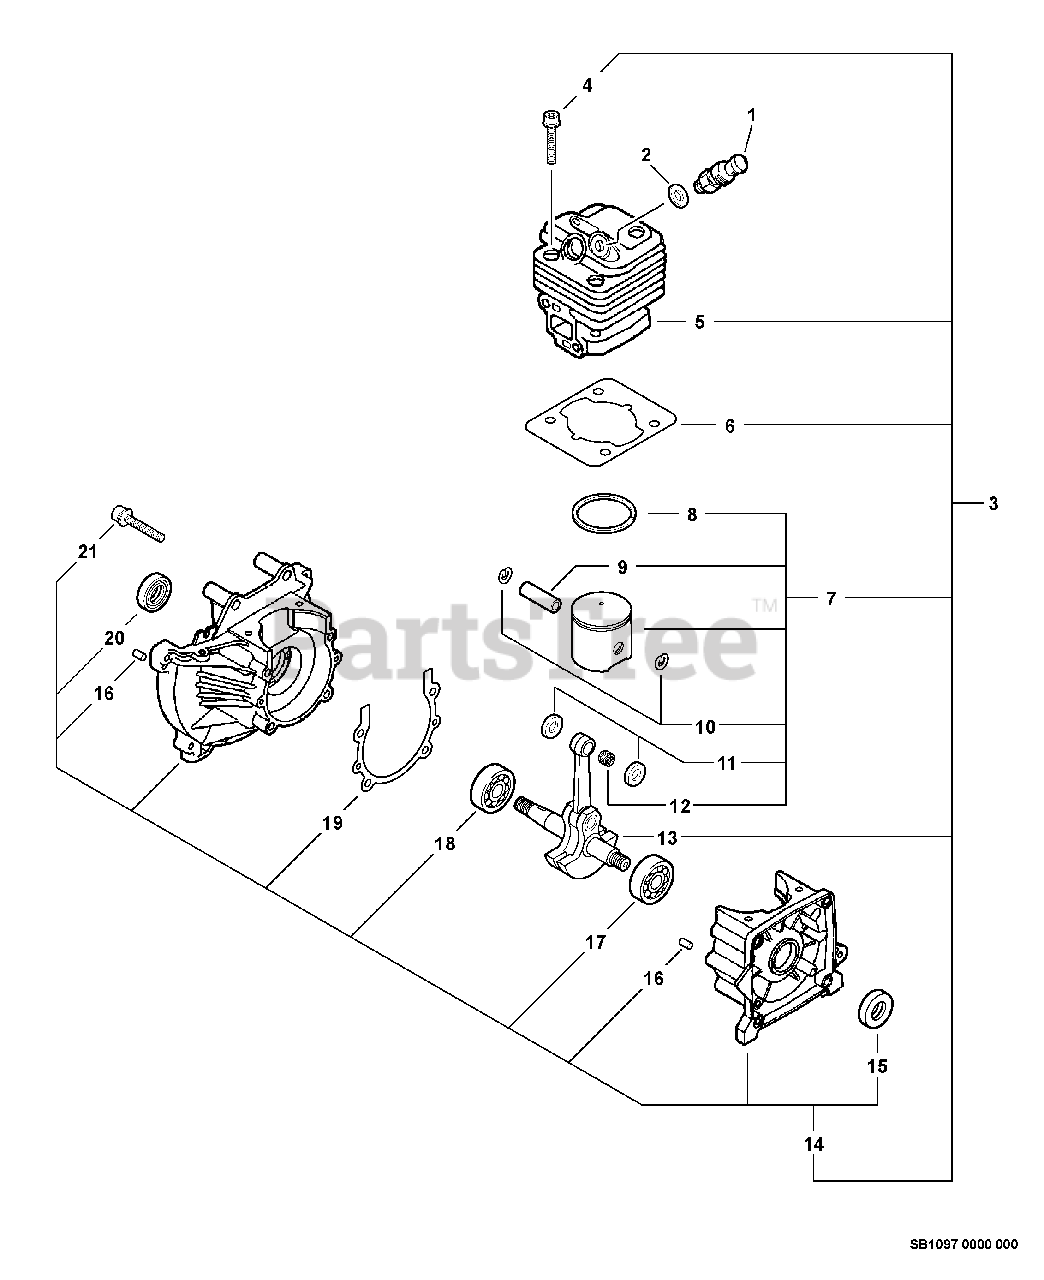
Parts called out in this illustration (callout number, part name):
1	VALVE, DECOMPRESSION
2	GASKET
3	SHORT BLOCK
4	BOLT 5×20
5	CYLINDER
6	GASKET, CYLINDER
7	PISTON KIT
8	RING, PISTON
9	PIN, PISTON 10
10	RING, SNAP Ø10
11	WASHER, THRUST
12	BEARING, NEEDLE 10
13	CRANKSHAFT ASSY
14	CRANKCASE KIT
15	SEAL, OIL 12
16	PIN, LOCATING 4×8
17	BEARING, BALL - 6201 C3
18	BEARING, BALL 6202
19	GASKET, CRANKCASE
20	SEAL, OIL
21	BOLT M5×35
